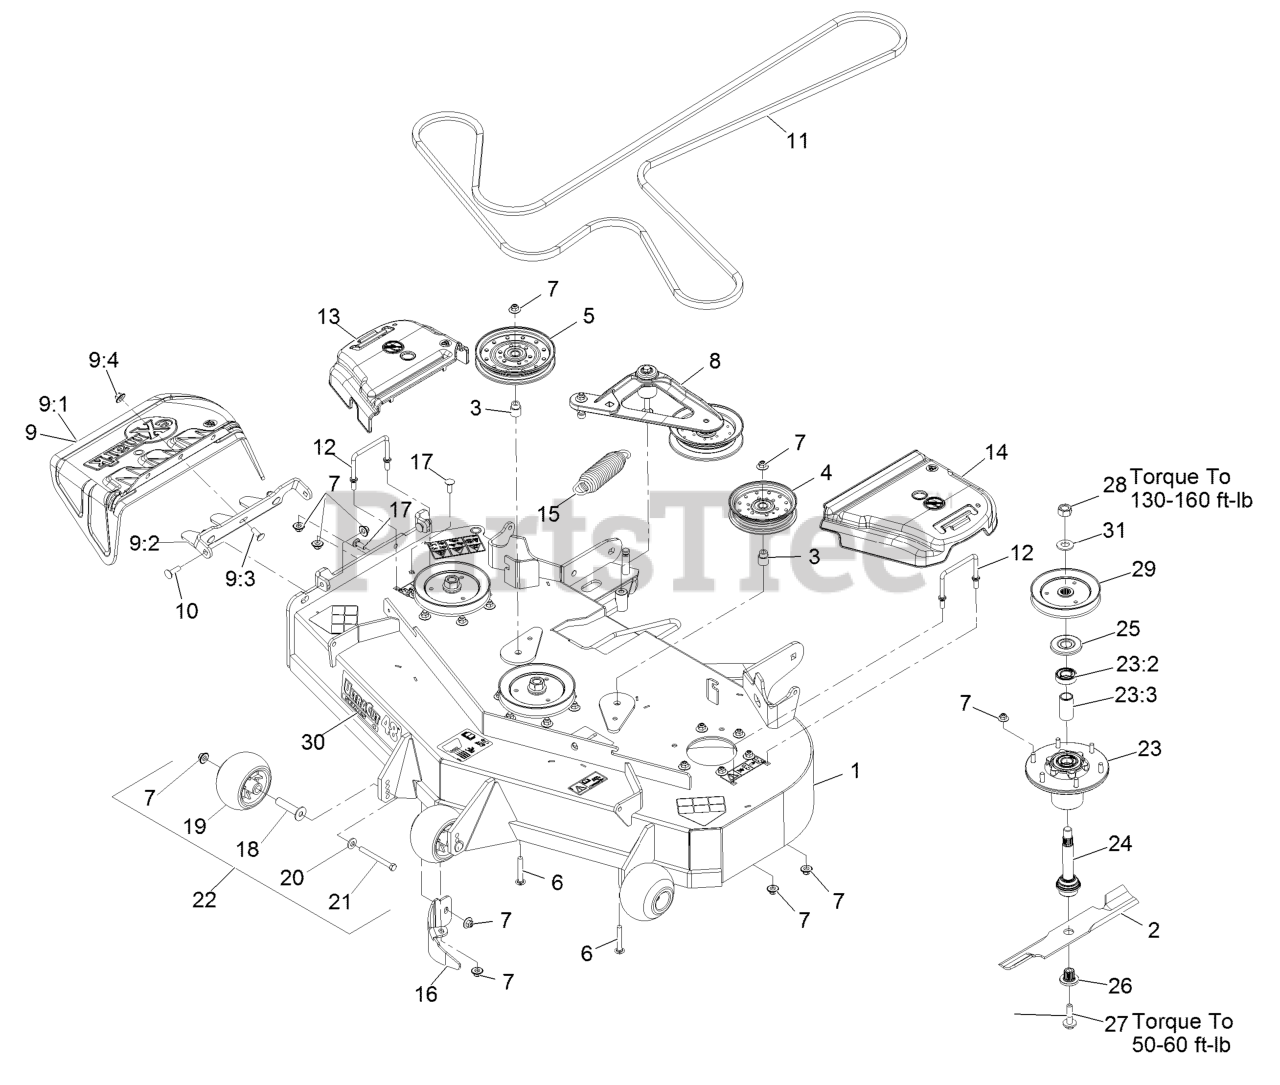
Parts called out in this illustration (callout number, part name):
1	ASM,DECK W/DECALS 48
3	BUSHING-IDLER
6	SCREW-CARR
7	Nut-Nyloc 3/8-16 Flg
8	DECK IDLER ASM
9	ASM,DISCHARGE CHUTE
9:1	CHUTE,DISCHARGE
9:2	BRACKET,DISCHARGE CHUTE
9:3	SCREW-CARR
9:4	Nut-Nyloc 3/8-16 Flg
10	Bolt-Carriage 3/8-16 X 1 1/4
11	BELT
12	WIREFORM-COVER
13	COVER-BELT, RH
14	COVER-BELT, LH
15	SPRING-EXTENSION
16	BAFFLE-DOGLEG,LZS LZX VT4
17	SCREW-CARR
18	AXLE, ROLLER
19	ROLLER-SCALP, ANTI
20	WASHER-BELLEVILLE
21	SCREW-HH 3/8-16 X 3 3/4 GR 8
22	KIT, ANTI-SCALP ROLLER
23	ASM-CUTTER HSG WITH BEARINGS
23:2	BEARING-BALL
23:3	SPACER-BEARING
24	ASM-SPINDLE AND SEAL
25	GUARD,BEARING TOP .989
26	BUSHING,SPLINED
27	SCREW,SEMS 1/2-20 X 2.19
28	NUT-HEX
29	SHEAVE,BLADE DRIVE 5.90
30	DECAL,ULTRACUT 48 SERIES
